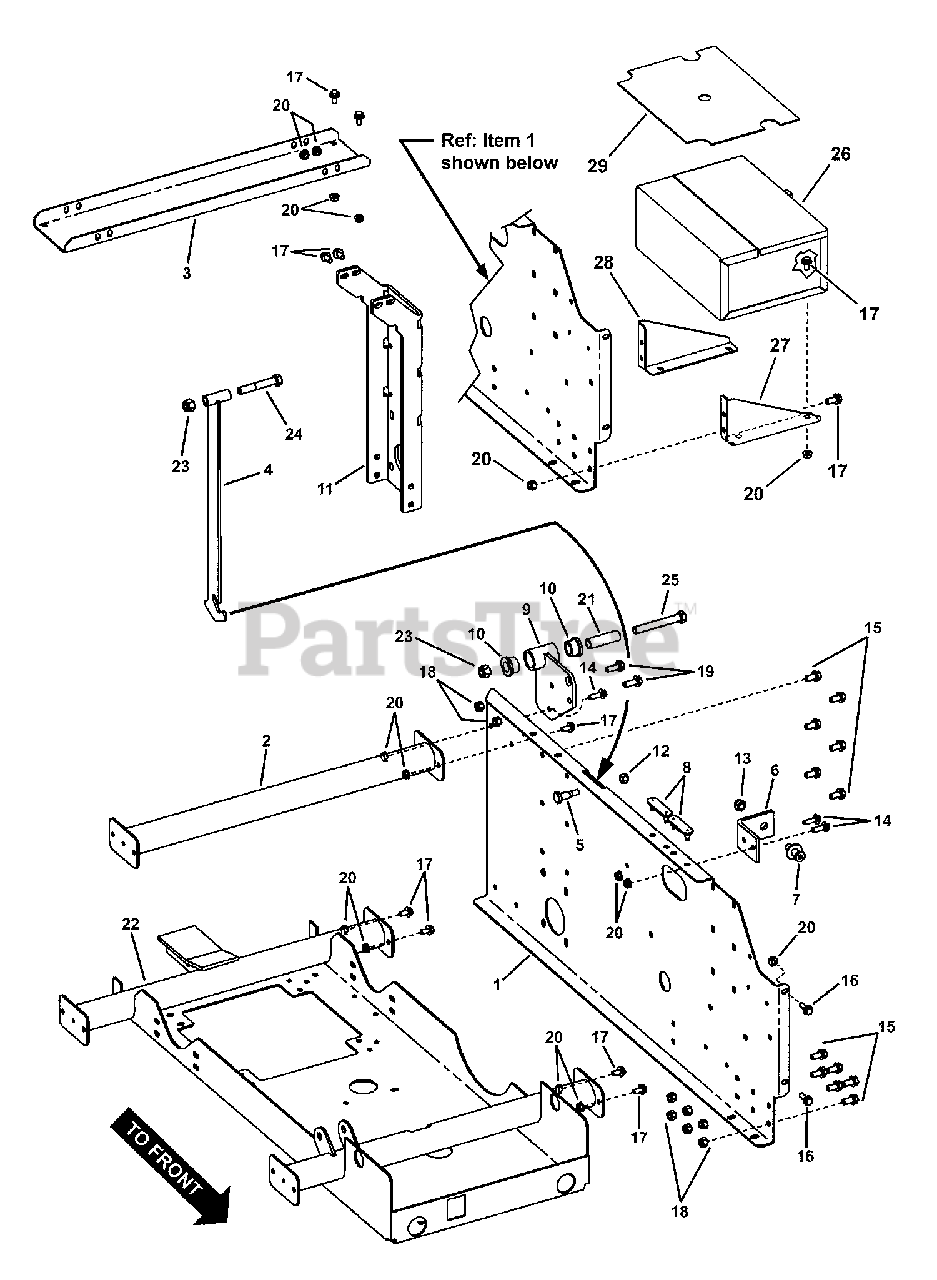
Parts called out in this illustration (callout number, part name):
1	FRAME, Rear LH (Red)
1	FRAME, Rear, LH (Green)
2	WELDMENT, Tube Brace (Flat Black)
2	WELDMENT, Tube Brace (Green)
3	CHANNEL, Frame Stiffener (Red)
3	CHANNEL, Frame Stiffener (Camo)
4	WELDMENT, Bed Prop
5	BOLT, 3/8-24 x .760 Hex Head, Shoulder, GR 5
6	BRACKET, Bed Latch
7	PIN, Bed Latch Striker (7/16-14 thread)
8	BUMPER, Rubber
9	WELDMENT, Dump Bed Pivot (Red)
9	WELDMENT, Dump Bed Pivot (Green)
10	BUSHING, Suspension
11	STIFFENER, CVT Frame (Red)
11	STIFFENER, CVT Frame (Green)
12	NUT, 3/8-24 Hex Nyloc
13	NUT, 7/16-14, Hex Nyloc
14	BOLT, 5/16-18 x 1" Hex Flange Lock
15	SCREW, 3/8-16 x 3/4" Hex Washer Self-Tap
16	BOLT, 5/16-18 x 7/8" Hex Flange Lock
17	BOLT, 5/16-18 x 5/8" Hex Flange Lock, GR 5
18	NUT, 3/8-16 Hex Nyloc
19	BOLT, 3/8-16 x 1" Hex Flange Lock, GR 5
20	NUT, 5/16-18 Hex Flange Lock, GR 5
21	SLEEVE, Suspension
22	WELDMENT, Drive Base
23	NUT, 1/2-13 Hex Nyloc
24	SCREW, 1/2-13 x 3" Hex Head Cap
25	BOLT, 1/2-13 x 3-3/4" Hex Head, GR 5
26	TOOLBOX, Turf/Trail Cruiser (Black)
27	BRACKET, Toolbox, LH (Red)
27	BRACKET, Toolbox, LH (Green)
28	BRACKET, Toolbox, RH (Red)
28	BRACKET, Toolbox, RH (Green)
29	MAT, Toolbox
